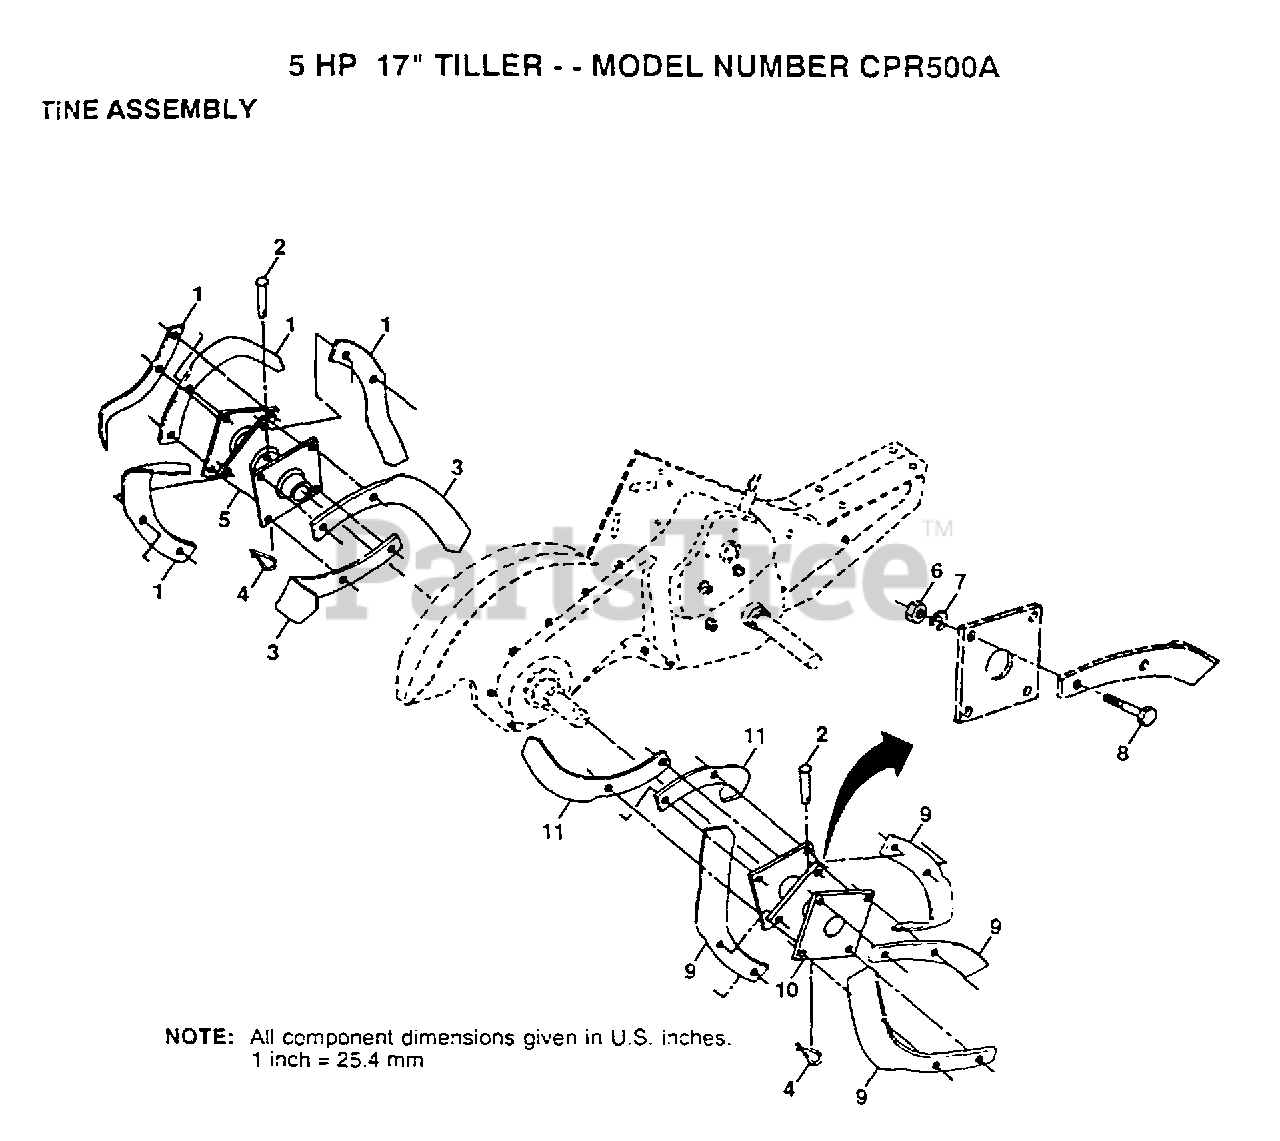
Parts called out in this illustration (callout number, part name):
2	PIN.CLEVIS.SHEAR
3	"TINE.LH.12"""
4	RETAINER.SPRING
5	HUB&PLATE ASM LH
7	LOCKWASHER
8	BOLT
10	HUB&PLATE ASM RH
11	"TINE.RH.12"""
